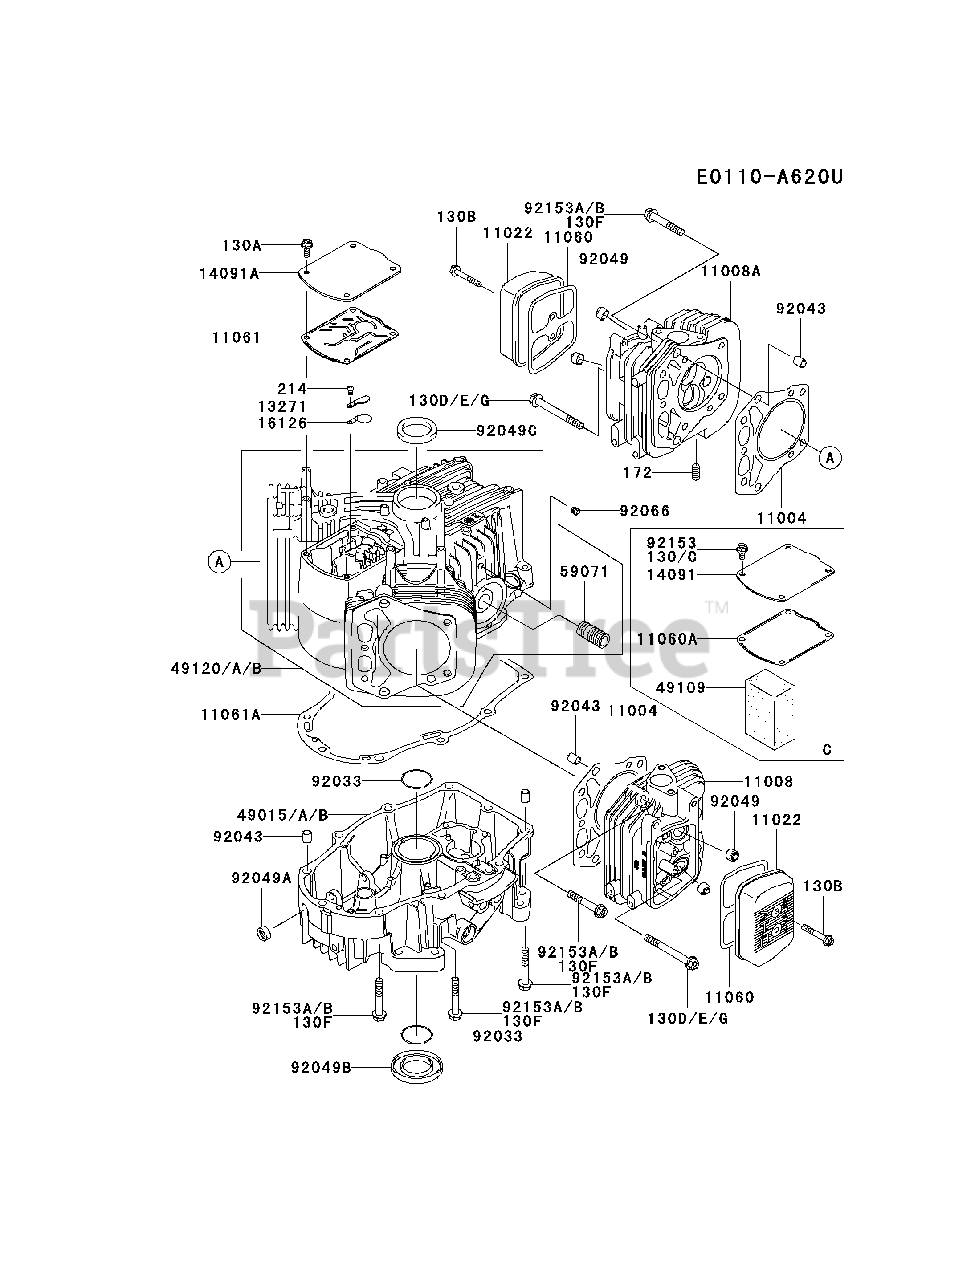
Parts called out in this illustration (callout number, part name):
130	BOLT-FLANGED,6X12
130A	BOLT-FLANGED,6X16
130B	BOLT-FLANGED,6X40
130C	BOLT-FLANGED,6X12
130E	BOLT-FLANGED,8X75
130F	BOLT-FLANGED,8X50
130G	BOLT-FLANGED,8X75
172	BOLT-STUD,8X18
214	SCREW-PAN+-,4X8
